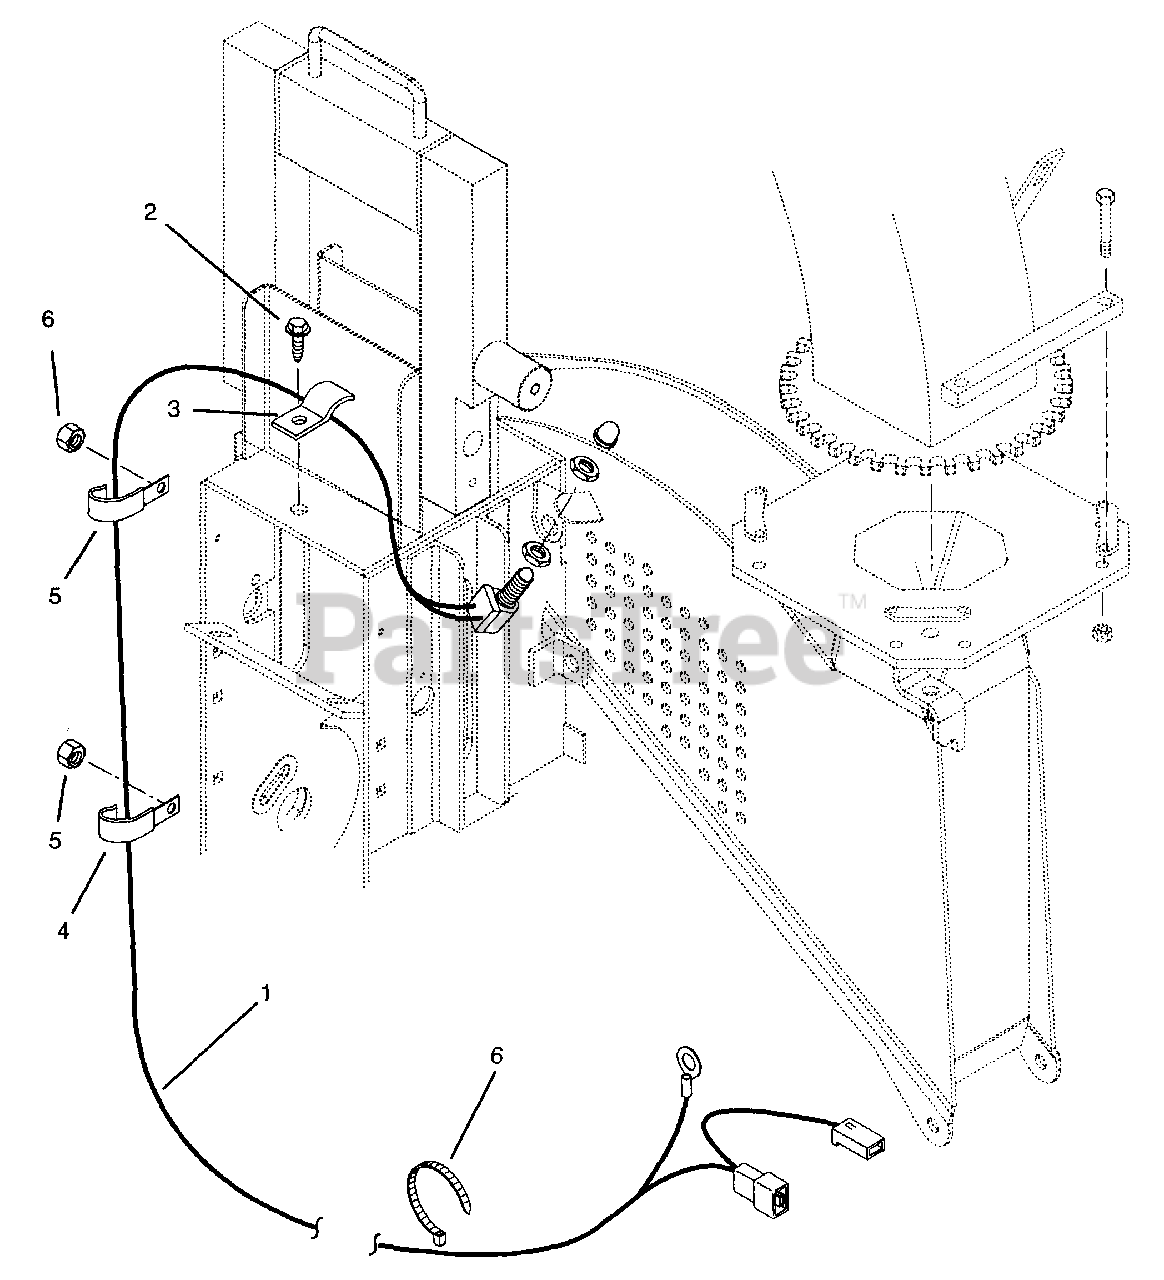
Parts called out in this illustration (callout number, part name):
1	Harness-Wiring 625LR Safety Switch
2	Screw-Tapping .25-20 x .50 Hex Washer Head
5	Nut-Locking-Center .38-16
6	Tie Wrap
